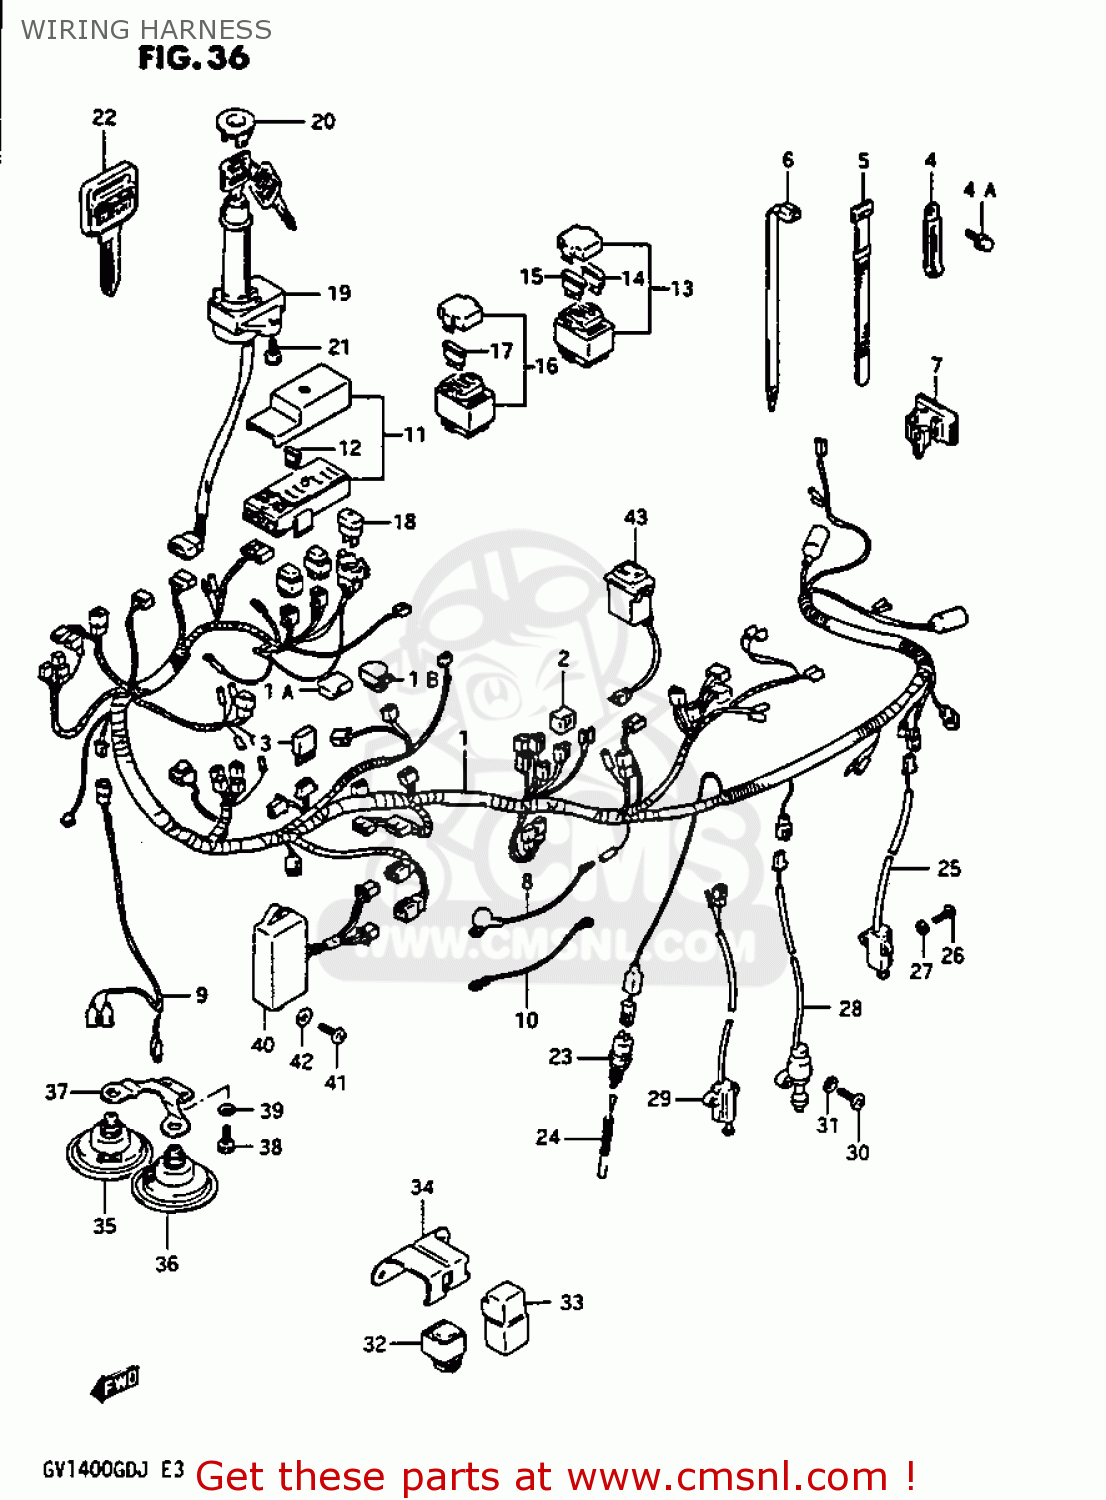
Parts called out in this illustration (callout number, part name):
1	HARNESS,WIRING
1A	CAP,BATTERY PLUS TERMINAL
1B	CAP,STARTER RELAY TERMINAL
2	RECTIFIER ASSY
3	DIODE(STANLEY DE8804)
4	CLAMP
4A	BOLT 8X12
5	CLAMP(L:120)
6	CLAMP(L:165)
7	CLAMP
8	WIRE,WATER TEMPERATURE GAUGE
9	WIRE
10	WIRE
11	BOX ASSEMBLY,FUSE
12	FUSE(10A)
13	BOX ASSEMBLY,FUSE
14	FUSE(3A)
15	FUSE(5A)
16	BOX ASSEMBLY,FUSE
17	FUSE(10A)
18	BREAKER ASSY,CIRCUT
19	SWITCH ASSEMBLY,IGNITION
20	CAP,IGNITION SWITCH
21	BOLT
22	KEY,BLANK
23	SWITCH ASSY,STOP LAMP
24	SPRING
25	SWITCH ASSEMBLY,SIDE STAND
26	SCREW
27	WASHER,LOCK
28	SWITCH ASSEMBLY,SIDE STAND
29	SWITCH ASSEMBLY,SIDE STAND
30	SCREW
31	WASHER,LOCK
32	RELAY ASSY
33	RELAY ASSY
34	BRACKET
35	HORN,HIGH TONE
36	HORN,LOW TONE
37	BRACKET,HORN
38	BOLT
39	WASHER,LOCK
40	RELAY ASSEMBLY,LAMP OUTAGE
41	SCREW
42	WASHER
43	SWITCH ASSEMBLY,AUTO LEVEL
